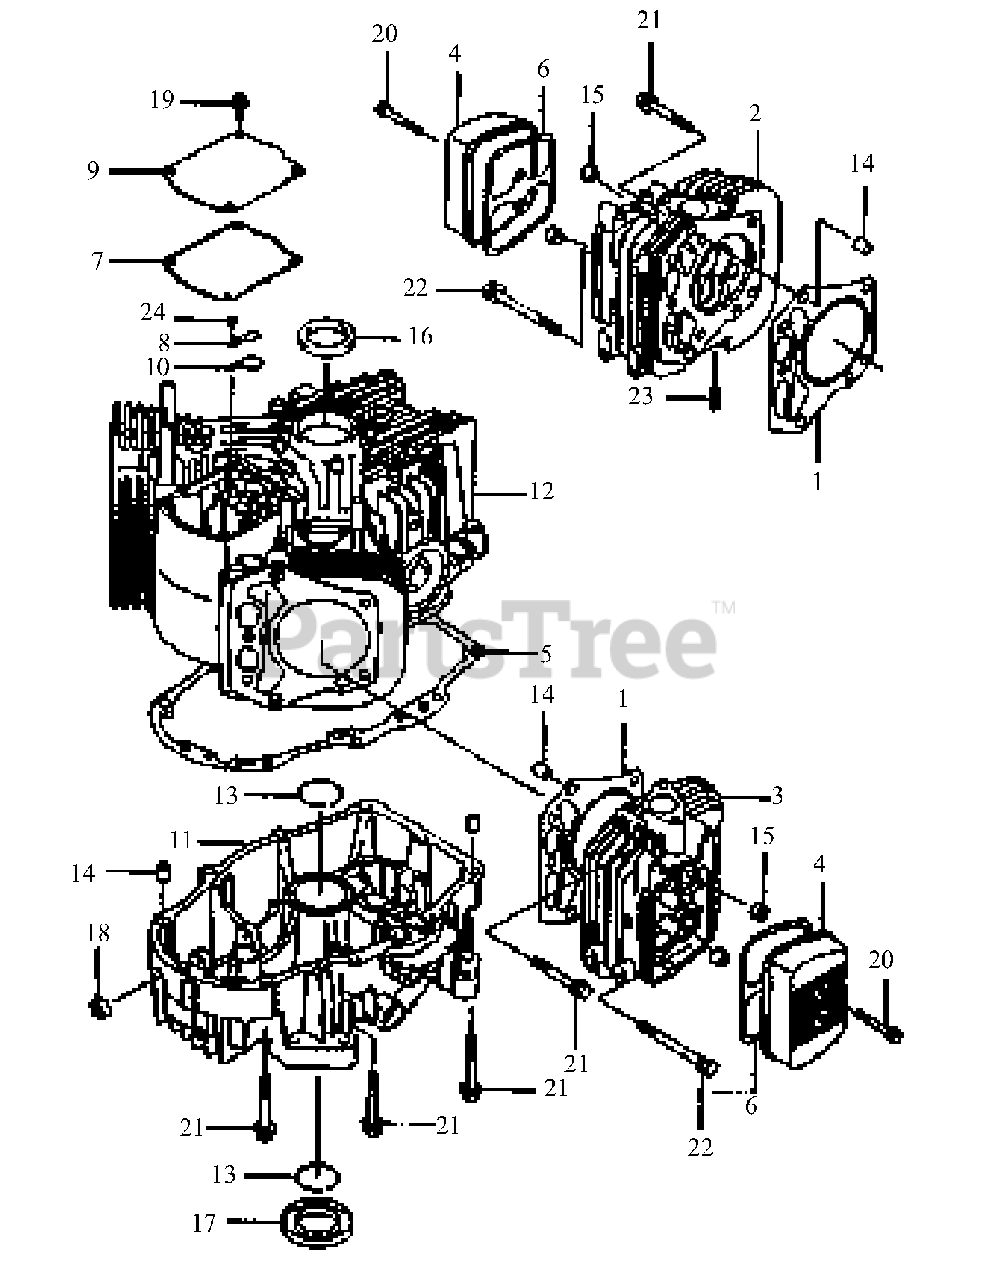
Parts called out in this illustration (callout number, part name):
2	Head-Cylinder # 1
3	Head-Cylinder # 2
4	Case-Rocker
5	Gasket, Crankcase
6	Gasket-Rocker Cover
7	Gasket-Breather
11	Cover-Crankcase
12	Crankcase
13	Ring, Snap
